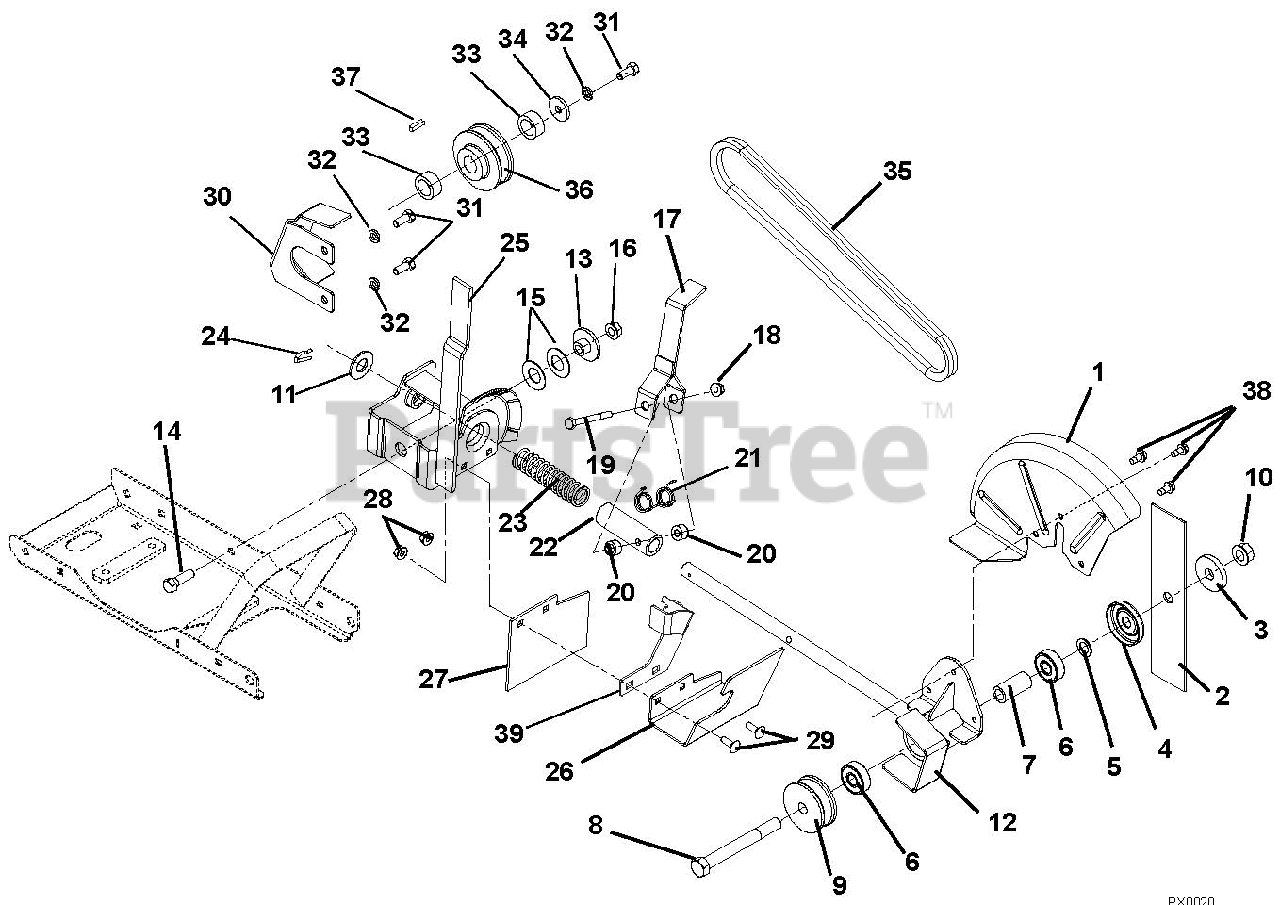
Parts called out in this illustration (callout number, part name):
1	GUARD,BLADE
2	BLADE, EDGER-9"
3	WSHR-FL-STL .515X1.625X.250 YZ
4	SLINGER, BEARING
5	WSHR-FL-STL .52X.827X.062 YWZC
6	BRG-BALL .500X1.38X.437
7	BSHG-SLV .500X.750X1.560
8	@BLT-HEX .50-13X4.50 GR5 YWZC
9	PULLEY, BLADE
10	@NUT-LK-TOP-FLG .50-13 YWZC
11	@WSHR-FL-STL.656X1.31X.095 YWZ
12	SPINDLE,CUTTER HEAD
13	BSHG,FLG .384X.635X.41X1.49
14	@BLT-HEX .38-16X1.25 GR5 YWZC
15	WASHER, BELLEVILLE
16	@NUT-LK-TOP-FLG .38-16 YWZC
17	LEVER,TILT
18	@NUT-LK-TOP-FLG .25-20 YWZC
19	@BLT-HEX .25-20X2.50 GR5 YWZC
20	BSHG,FLG .263X.393X.18X.625
21	SPRING, TORSION
22	COLLAR, SPRG
23	SPRING, COMPRESSION
24	PIN, SPRING CLIP
25	MOUNT,CUTTER HEAD PIVOT
27	FLAP, RUBBER
28	@NUT-LK-TOP-FLG .25-20 YWZC
29	@BLT-RDHDSQNK .25-20X.75 G5YZ
30	BELT FINGER,ENGINE
31	BLT-HEX .31-24X.75 YWZC GR5
32	WSHR-LK .312X.097 HVY YWZC
33	BSHG-SLV .766 X 1.125 X .500
34	WSHR-FL-STL .344X1.125X.135
35	V-BELT, 4L-WRAPPED
36	PULLEY, ENGINE
37	KEY-SQ .188X.75X.188
38	SCR-TAP .25-20X.50 HWH TR YWZ
39	BRACKET,LIMIT
